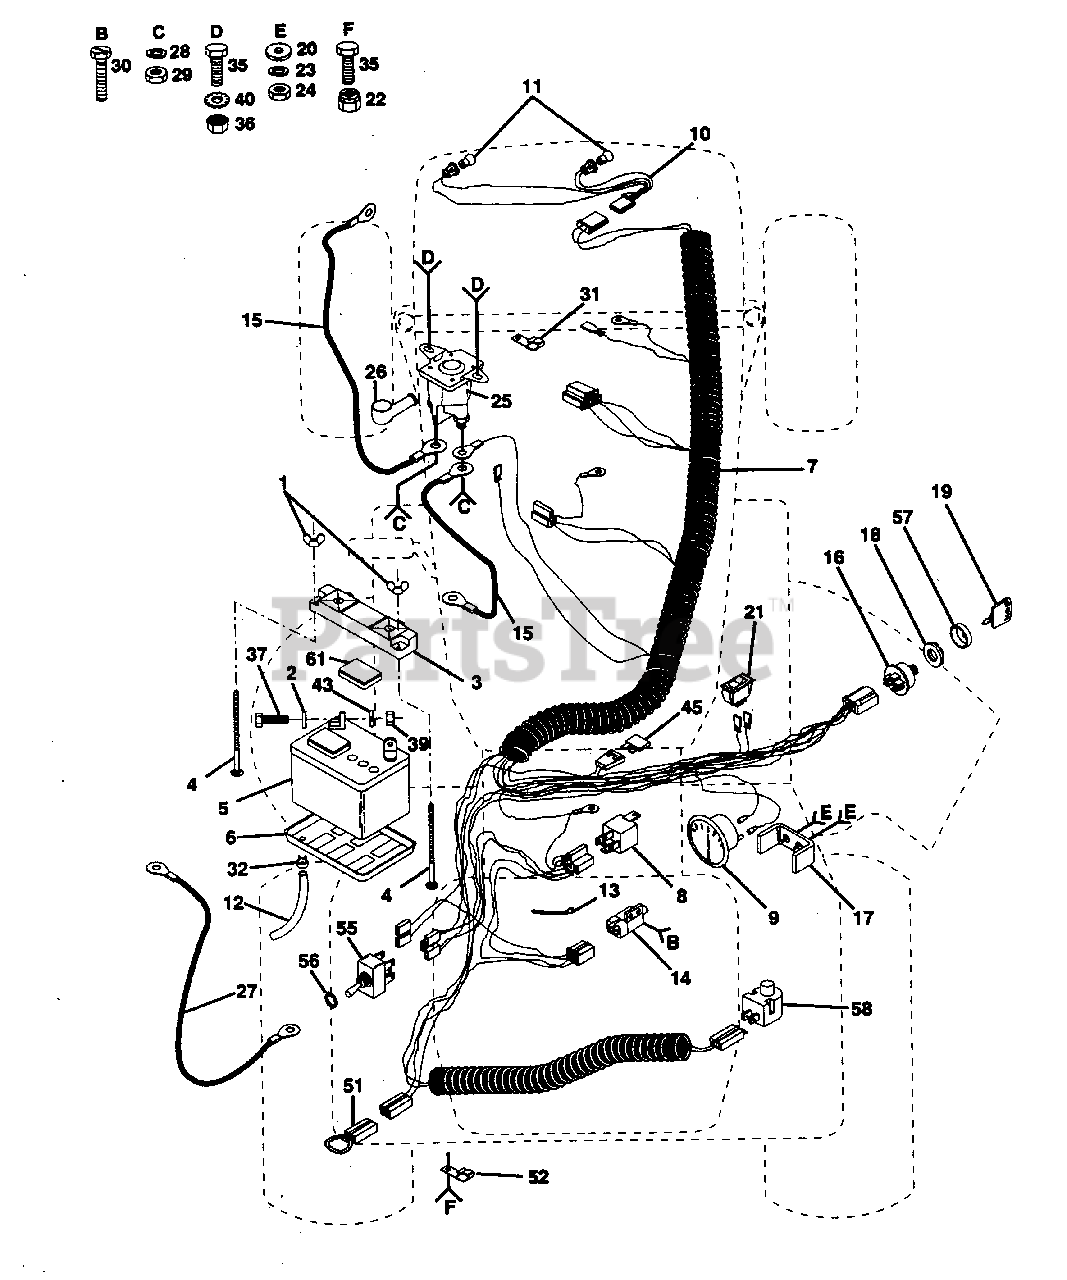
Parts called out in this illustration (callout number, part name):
1	Wing Nut 1/4-20 (AYP part number)
2	Washer 9/32 x 5/8 x 16 Ga (AYP part number)
3	Guard, Terminal (AYP part number)
4	Battery Bolt (Bolt, Carriage, Rd. Hd. Sq. Neck) 1/4-20 x 7-1/21 (AYP part number)
5	Battery (AYP part number)
6	Battery Tray (AYP part number)
7	Harness, Ignition (AYP part number)
8	Relay (AYP part number)
9	Ammeter (AYP part number)
10	Harness, Light Socket (AYP part number)
11	Bulb, Light (AYP part number)
12	Tube, Battery Tray (AYP part number)
13	Cable Tie (AYP part number)
14	Switch, Interlock, Clutch (AYP part number)
15	Cable, Battery (Battery to Solenoid) (AYP part number)
16	Ignition Switch (AYP part number)
17	Bracket, Ammeter
18	Nut, Ignition (AYP part number)
19	Key (AYP part number)
20	Washer 7/32 x 1/2 x 18 Gauge (AYP part number)
21	Switch, Light (AYP part number)
22	Nut, Crownlock 1/4-20 (AYP part number)
23	Washer, Lock (AYP part number)
24	Nut (AYP part number)
25	Solenoid (AYP part number)
26	Terminal Cover (AYP part number)
27	Cable, Battery (Battery to Ground) (AYP part number)
28	Washer, Lock (AYP part number)
29	Nut, Hex Jam 1/4 x 20 UNC (AYP part number)
30	Screw, Tap. Hex Hd. #10-24 UNC (AYP part number)
31	Clip, Fuel Line (AYP part number)
32	Clamp, Hose (AYP part number)
35	Bolt, Hex 1/4-20 x 1/2 Gr. 5 (AYP part number)
36	Nut, Keps, Hex 1/4-20 (AYP part number)
37	Bolt, Hex i/4-20 x 3/4 (AYP part number)
39	Nut, Hex 1/4-20 (AYP part number)
40	Washer, Lock 1/4 Ext. Tooth (AYP part number)
43	Washer, Lock 1/4 (AYP part number)
45	Fuse, 30 Amp. (AYP part number)
51	Loop, Wire Tiller Attachment (AYP part number)
52	Clip, Insulated (AYP part number)
55	Switch PTO (AYP part number)
56	Nut, Hex (AYP part number)
57	Cover Serv Key (AYP part number)
58	Switch, Plunger (AYP part number)
61	Caps, Battery Set (AYP part number)
